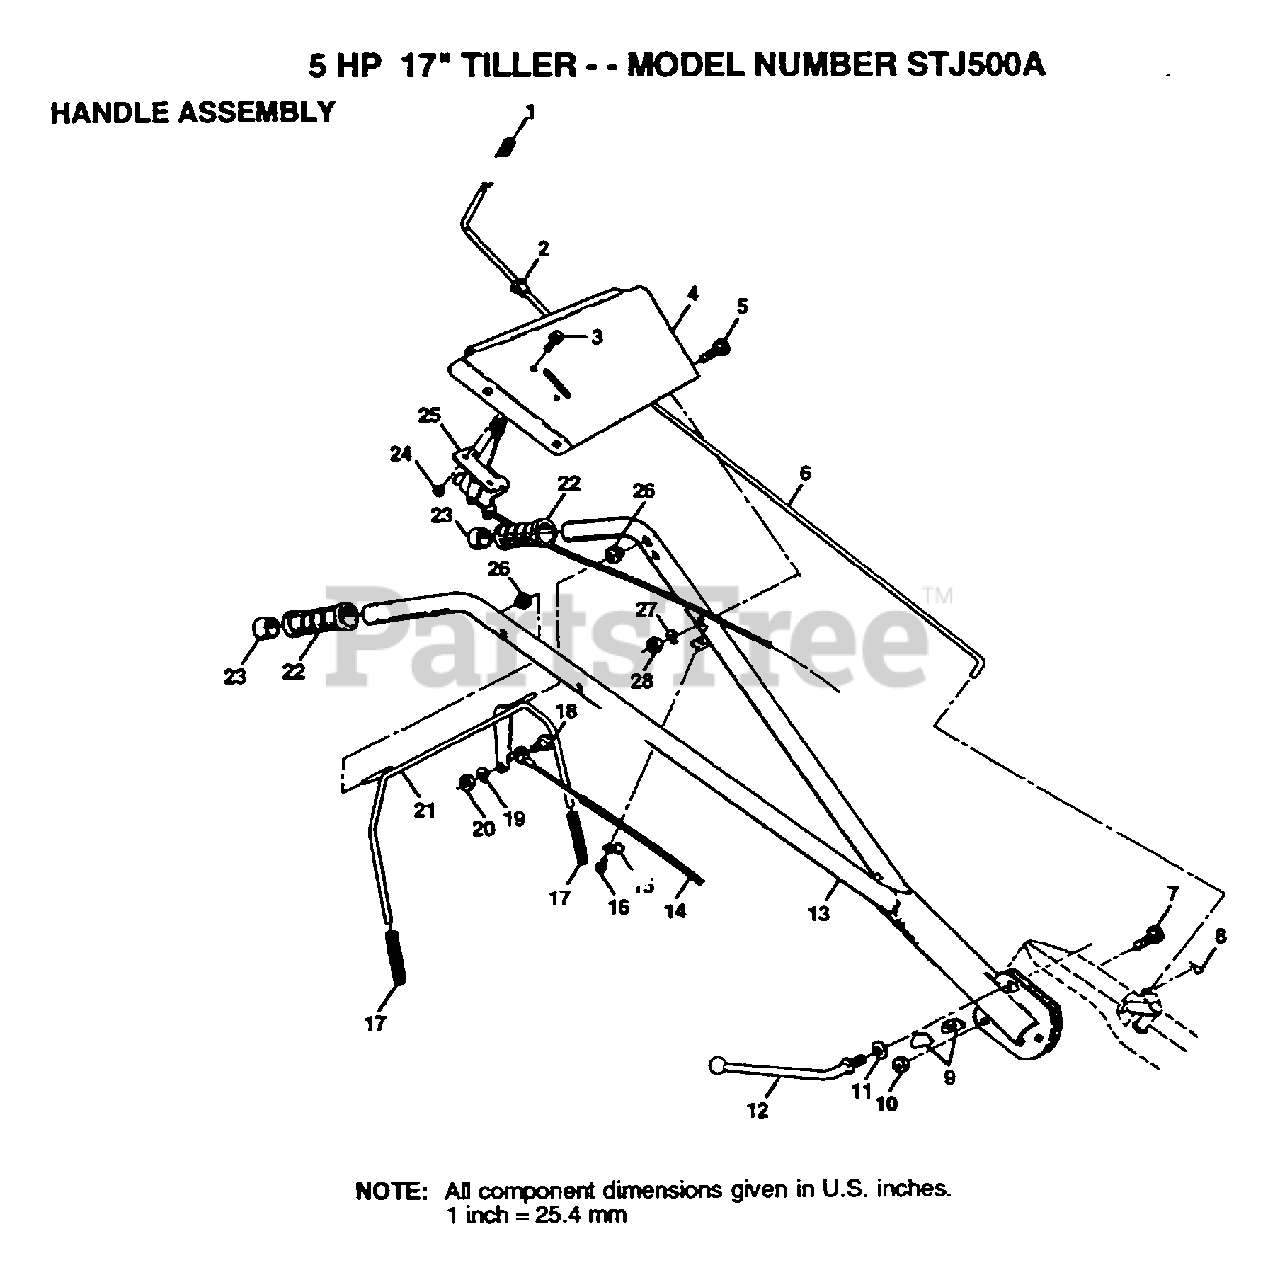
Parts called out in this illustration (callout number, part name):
1	GRIP TI
2	BUSHING
3	SCREW
5	BOLT CARRIAGE CRT
6	ROD SHIFT CRT
7	BOLT D
8	RETAINER M
9	LOCK CRT
10	LOCKNUT
11	WASHER CRT
12	LEVER LOCK CRT
14	CABLE.CLUTCH.CRT
15	CONDIUT CLIP T
17	GRIP BAR CRT
18	SHOULDER BOLT ST
19	LOCKWASHER
21	HANDLE BAR CRT
23	CAP CRT
25	"CONT,THROTTLE"
27	LOCKWASHER
